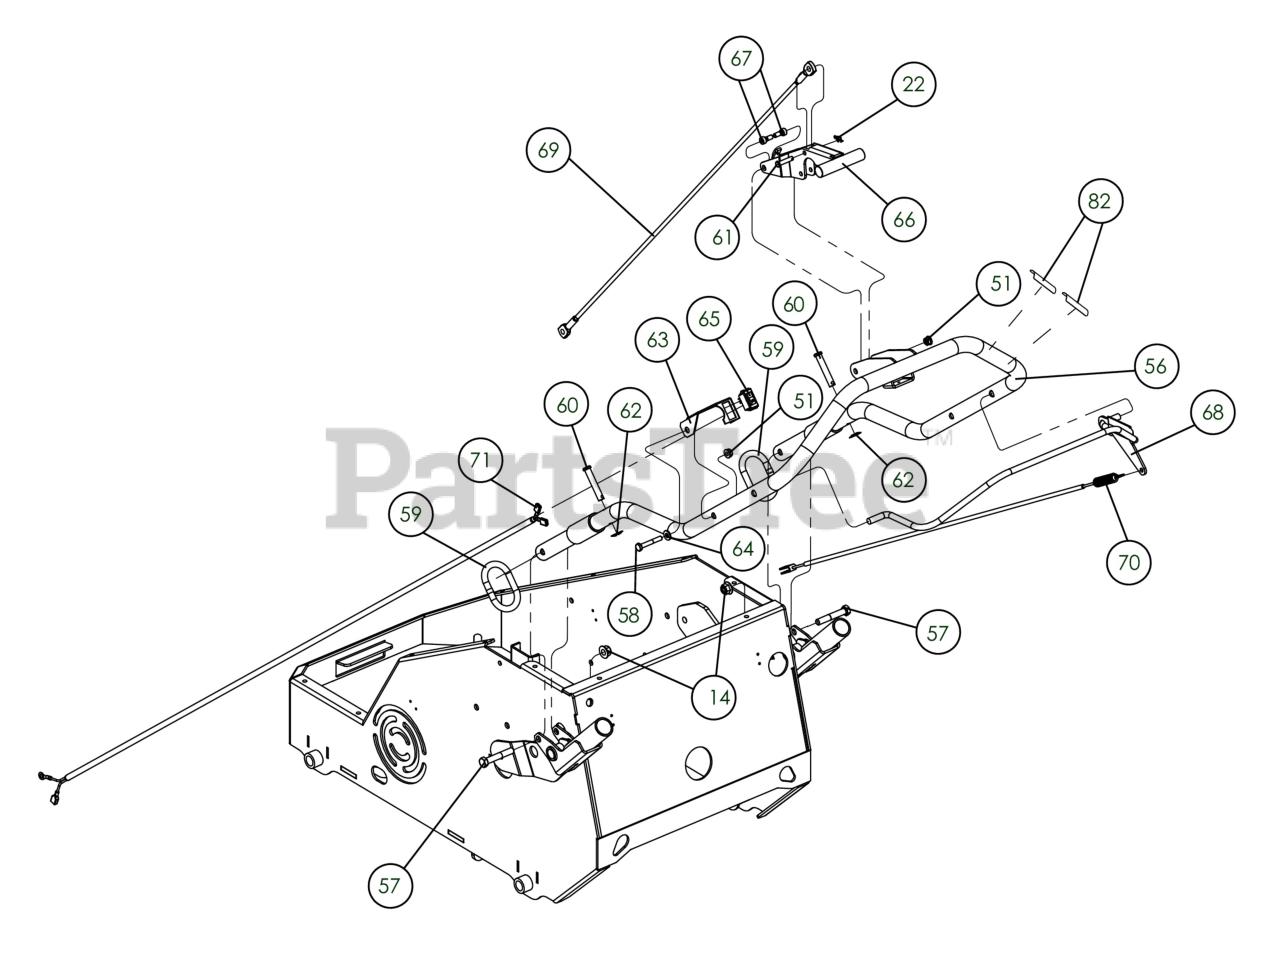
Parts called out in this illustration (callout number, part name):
14	NUT-HEX-NYLK, FLG .375"-16 ZP
22	1/4" RUE RING
51	NUT-HEX-NYLK, FLG .250"-20 ZP
56	WA, HANDLE PL1801
57	SCREWCAP 3/8"-16 X 2 1/4" HCS ZP GR 5
58	SCREWCAP 1/4"-20X1 3/4" HCS ZP
59	LOOP FOLDING HANDLE
60	PIN CLEVIS 3/8 X 2.125
61	CLEVIS PIN 1/4 X 1
62	RETAINER 3/8" BOLT PUSH NUT
63	BRACKET MOUNT SWITCH QB16SP
64	WASHER 1/4"SAE9/32"X5/8"X1/16"
65	SWITCH LKG RKR B&S #493521
66	RETRACTOR HANDLE (PL850)
67	SHOULDER BOLT, 5/16 DIA X 1/4
68	WA, BAIL PL1801
69	TINE LIFT CABLE, PL1801
70	CABLE CLUTCH 39"
71	HARNESS WIRE 60"
82	LABEL TINE ENGAGE PL
